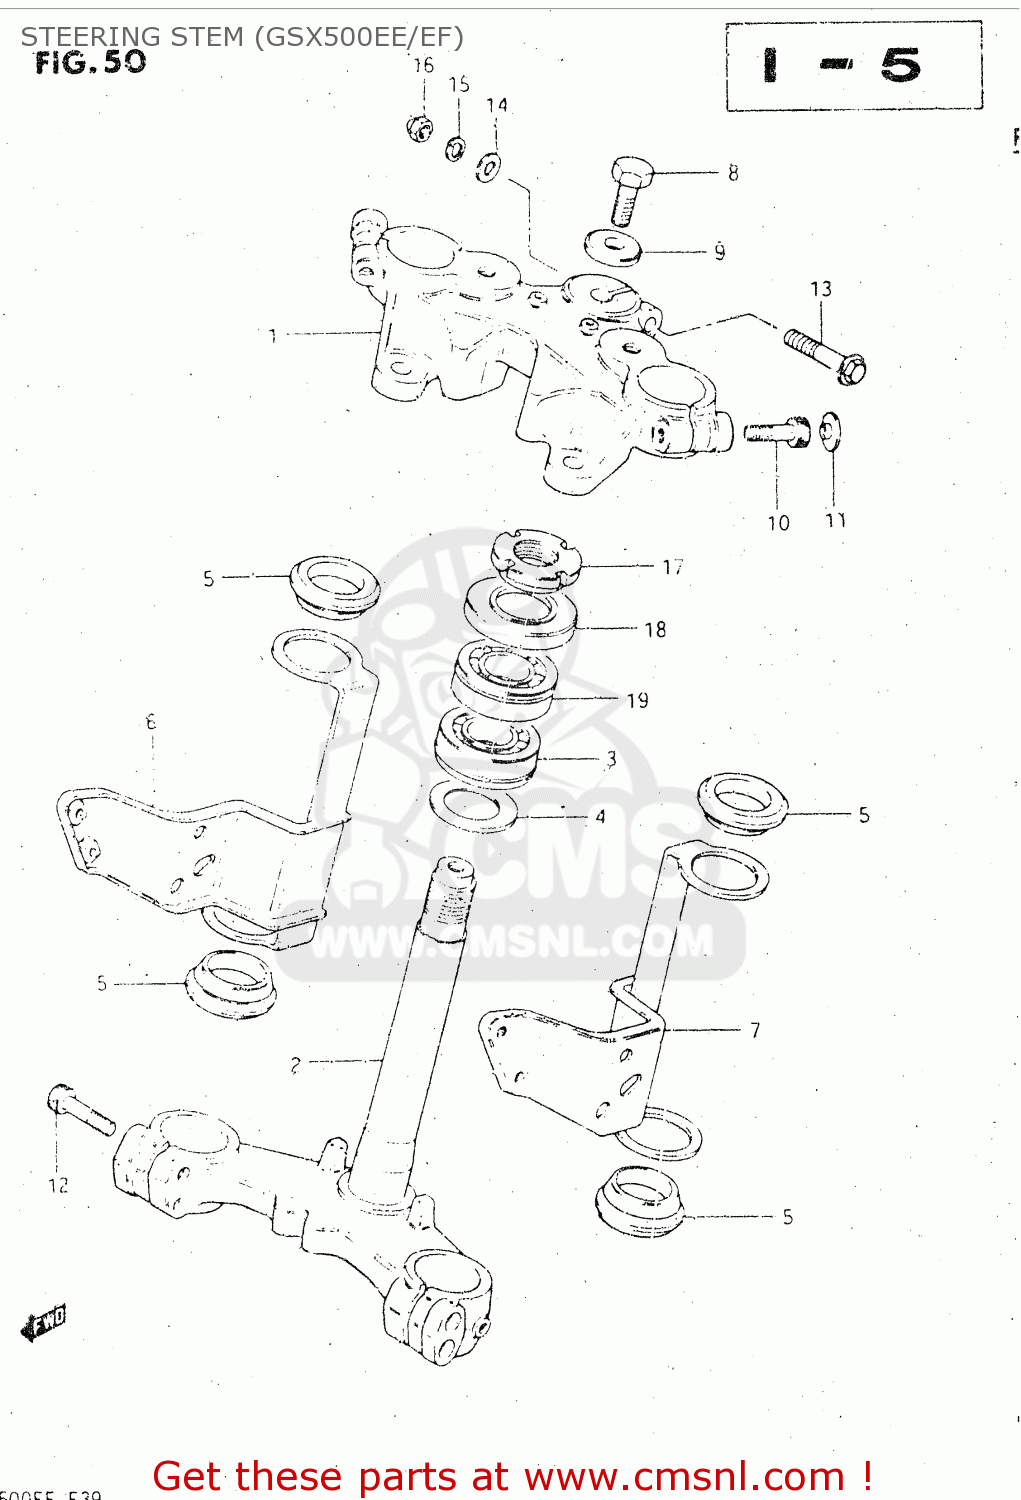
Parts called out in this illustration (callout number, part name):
1	HEAD,STEERING STEM
2	STEM,STEERING
3	BEARING
4	WASHER,THRUST
5	CUSHION,HEADLAMP BRACKET
6	BRACKET,HEADLAMP,RIGHT
7	BRACKET,HEADLAMP,LEFT
8	NUT,STEM HEAD
9	WASHER,STEERING STEM B
10	BOLT 10X35
11	CAP(OD:20)
12	BOLT, REAR (8X30)
13	BOLT, UPPER
14	WASHER
15	WASHER,LOCK,8.
16	NUT,M8X1.25X12
17	NUT,STEERING STEM
18	DUST SEAL,STEERING UPR
19	TAPER,ROLLER BEARING
